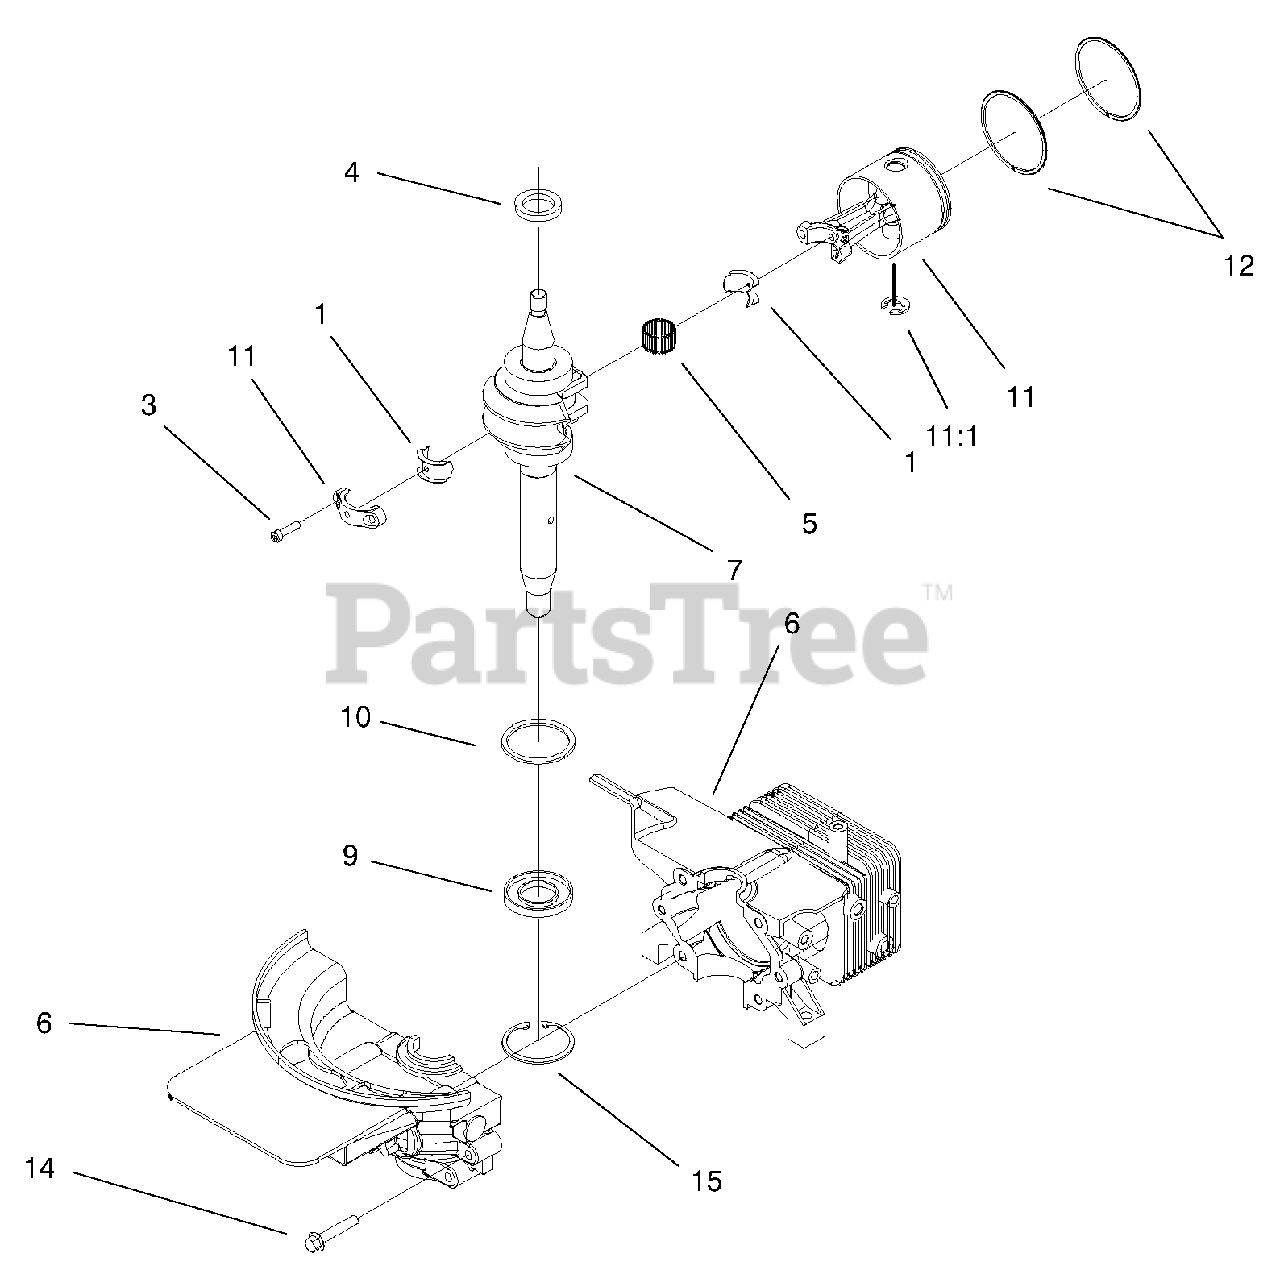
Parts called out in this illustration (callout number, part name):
1	Liner ASM
3	Screw-HSH Cap
4	Seal-Oil
5	Bearing-Needle
6	Cylinder And Crankcase ASM
7	Crankshaft And Bearing ASM
9	Seal-Oil
10	Ring-Retaining
11	Piston And Connecting Rod ASM
11:1	Ring-Retaining Vex
15	Ring-Retaining
